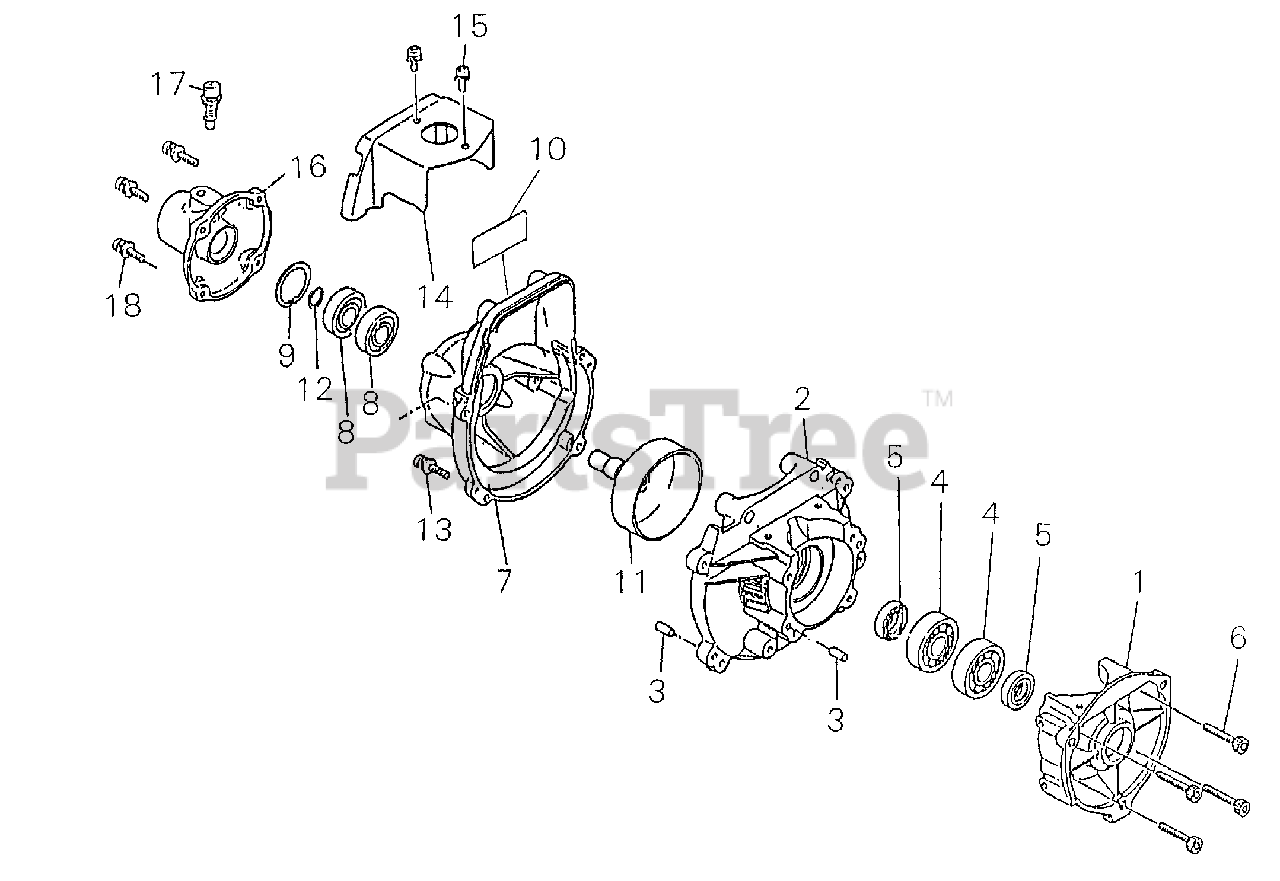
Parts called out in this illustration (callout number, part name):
1	CRANKCASE - REAR
2	CRANKCASE - FRONT
3	PIN - LOCATING
4	BEARING, BALL - 6201C3
5	SEAL, OIL - 12
6	SCREW - 5X25
7	CASE, FAN
8	BEARING, BALL - 6001DDU
9	RING, RETAINING - 28
10	LABEL - TRADE
11	DRUM, CLUTCH
12	RING, RETAINING
13	SCREW - 5X20
14	COVER, ENGINE
15	SCREW - 5X12
17	PIN ASSY
18	SCREW - 5X20
